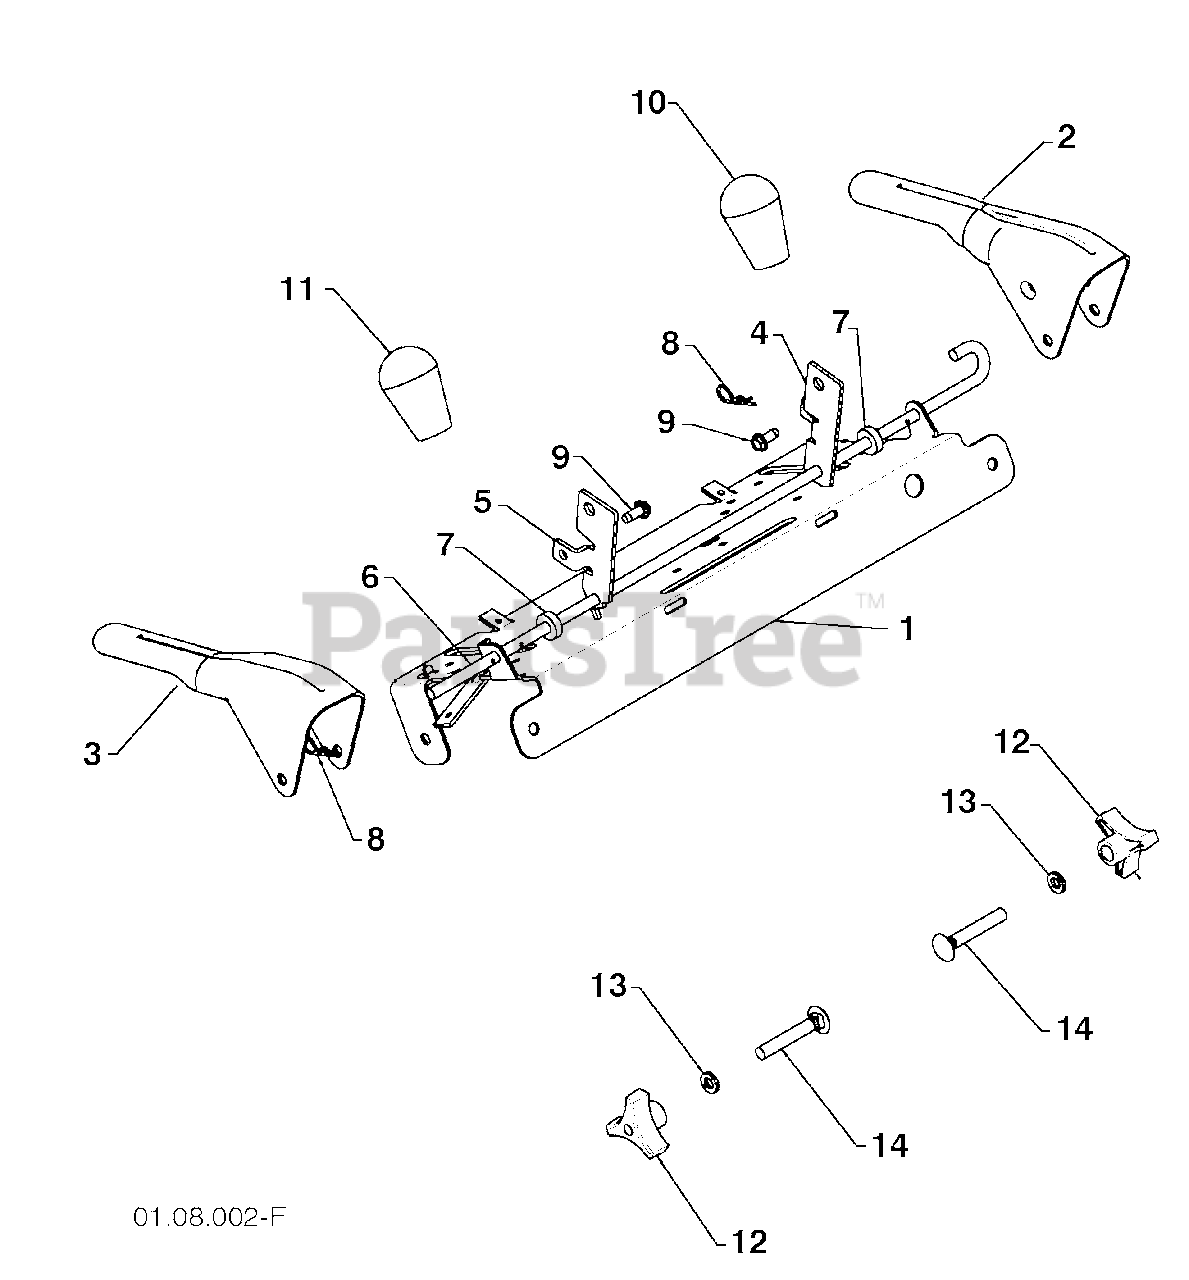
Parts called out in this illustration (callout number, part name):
1	CONTROL PANEL
2	CONTROL LEVER LH
3	CONTROL LEVER RH
4	TRACTION ROD ARM
5	IMPELLER ROD ARM
6	INTERLOCK BAIL
8	RETAINER
9	SCREW 1/4-20 X .62
10	KNOB BLACK
11	KNOB RED
12	HANDLE KNOB
13	WASHER 3/8
14	CARRIAGE BOLT 3/8-16 X 2.25
